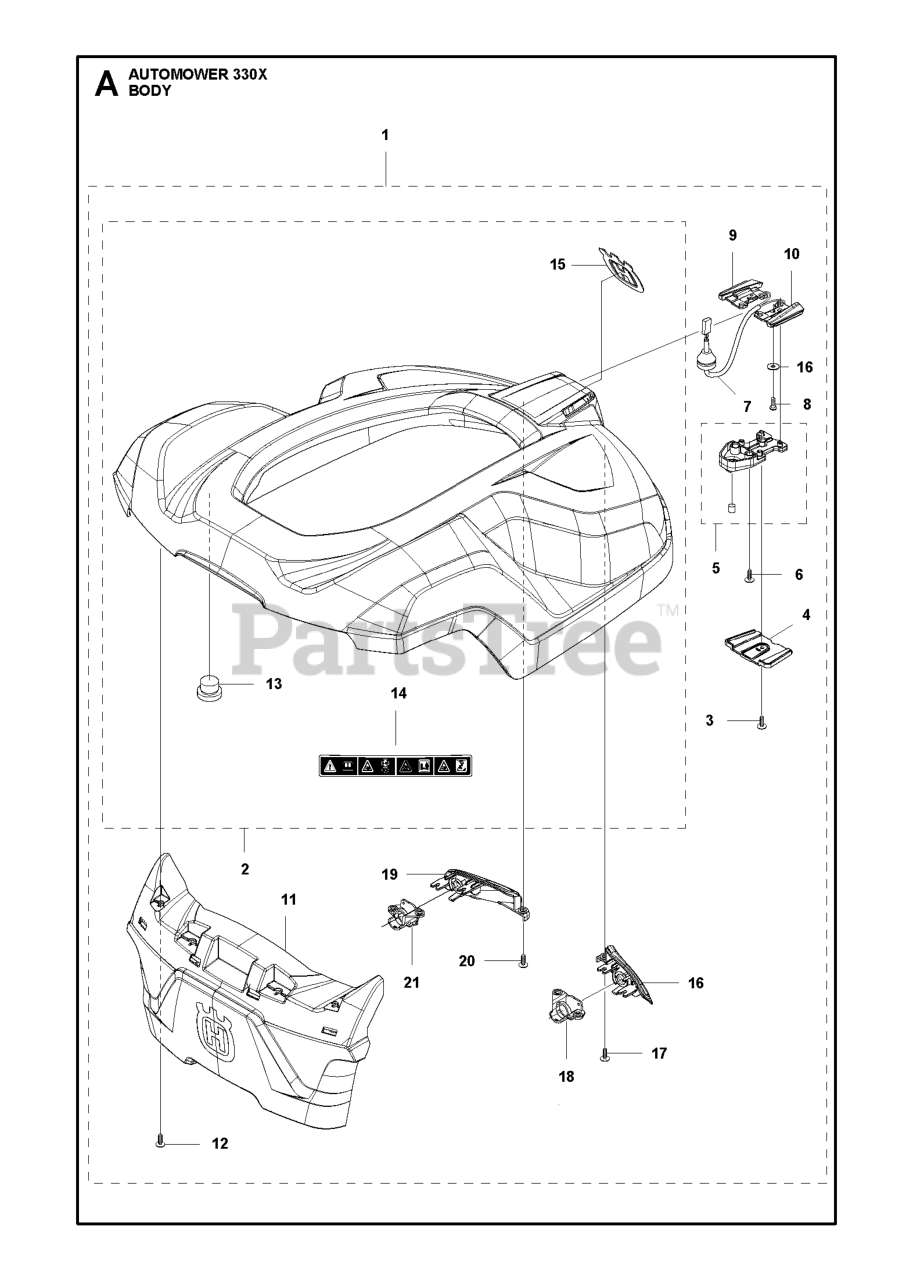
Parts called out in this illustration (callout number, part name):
2	BODY KIT GREY
3	SCREW 14MM
6	SCREW 14MM
11	BUMPER REAR
12	SCREW ITXPANT
13	CAP SNAPLOC
14	LABEL WARNING P15
15	DECAL HUSQVARNA CROWN HEIGHT 5
16	INSERT US-SENSOR RIGHT - GREY
17	SCREW 14MM
18	HOLDER US-SENSOR RIGHT, BLANK
19	INSERT US-SENSOR LEFT - GREY
20	SCREW 14MM
